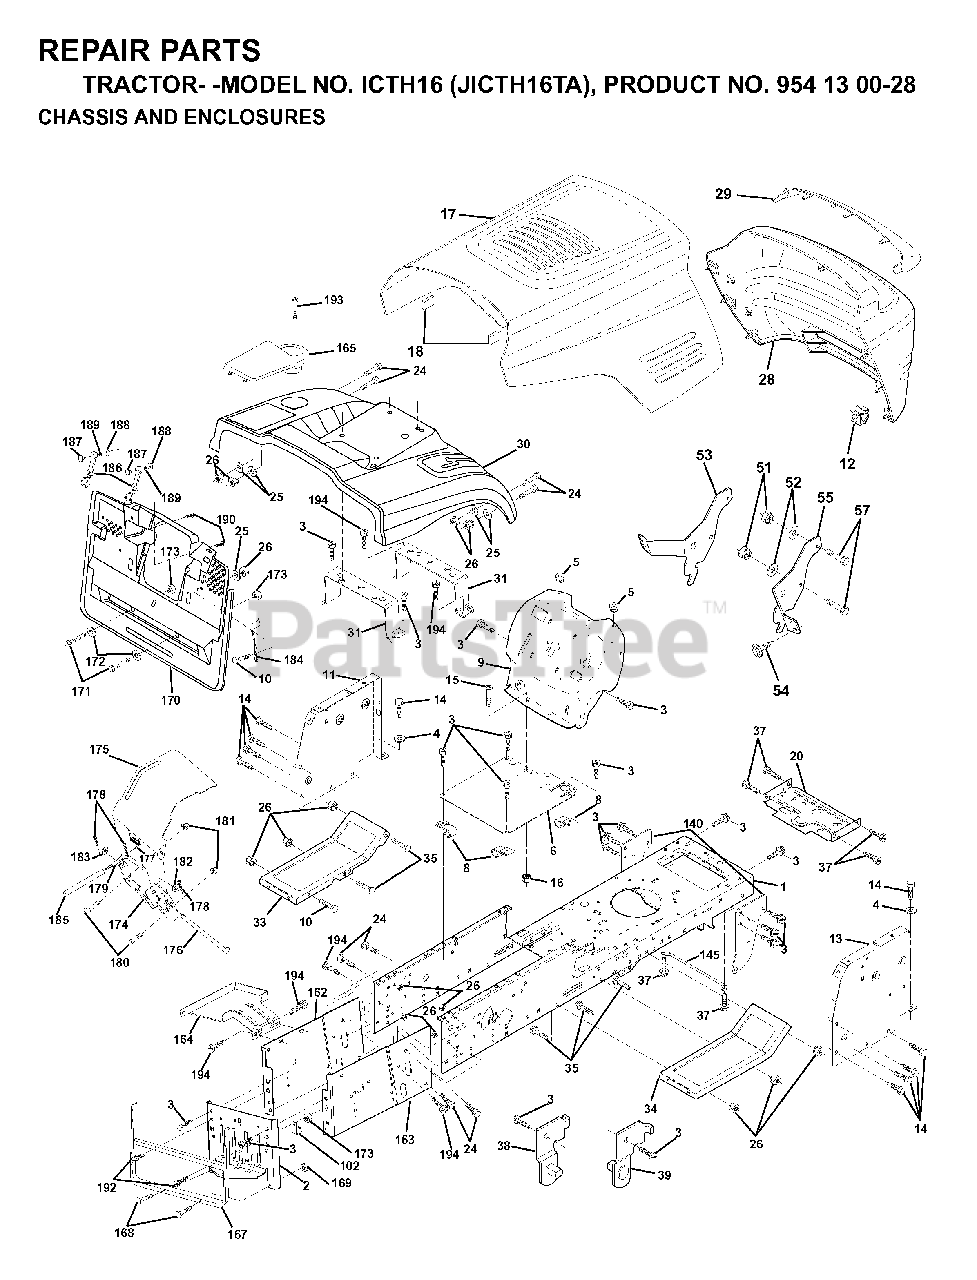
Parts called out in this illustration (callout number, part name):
3	SCREW
5	BUMPER.RUBBER.HOOD
6	SADDLE FLAT
8	CLIP,INSULATOR
10	BOLT D
11	PANEL DASH LH
13	DASH PANEL
14	SCREW LT
16	NUT
18	BUMPER HOOD T
20	PLATE MTG
24	BOLT
25	WASHER
26	NUT
31	BRACKET SUPPORT FENDER
35	BOLT
37	SCREW LT
38	BRACKET LH PIVOT
39	BRACKET RH PIVOT
51	LOCKNUT
52	WASHER
57	BOLT
102	CLIP T
140	BRACKET SUSPENSION FRONT
145	ROD PIVOT CHASSIS/HOOD
164	SUPPORT
168	BOLT.ROUND.HEAD.SQUARE.NECK
169	NUT T
170	COVER BACKPLATE
172	WASHER
176	HINGE PIN
177	SPRING COVER LH
178	COTTER PIN
179	ROD PIVOT
180	BOLT RB
181	LOCKNUT
184	BRACKET
185	TUBE LEVER
186	LATCH ASSY
187	WELDNUT
189	LOCKWASHER
190	SCREW
192	SCREW LT
193	SCREW LT
194	SCREW 3/8-16X3/4
